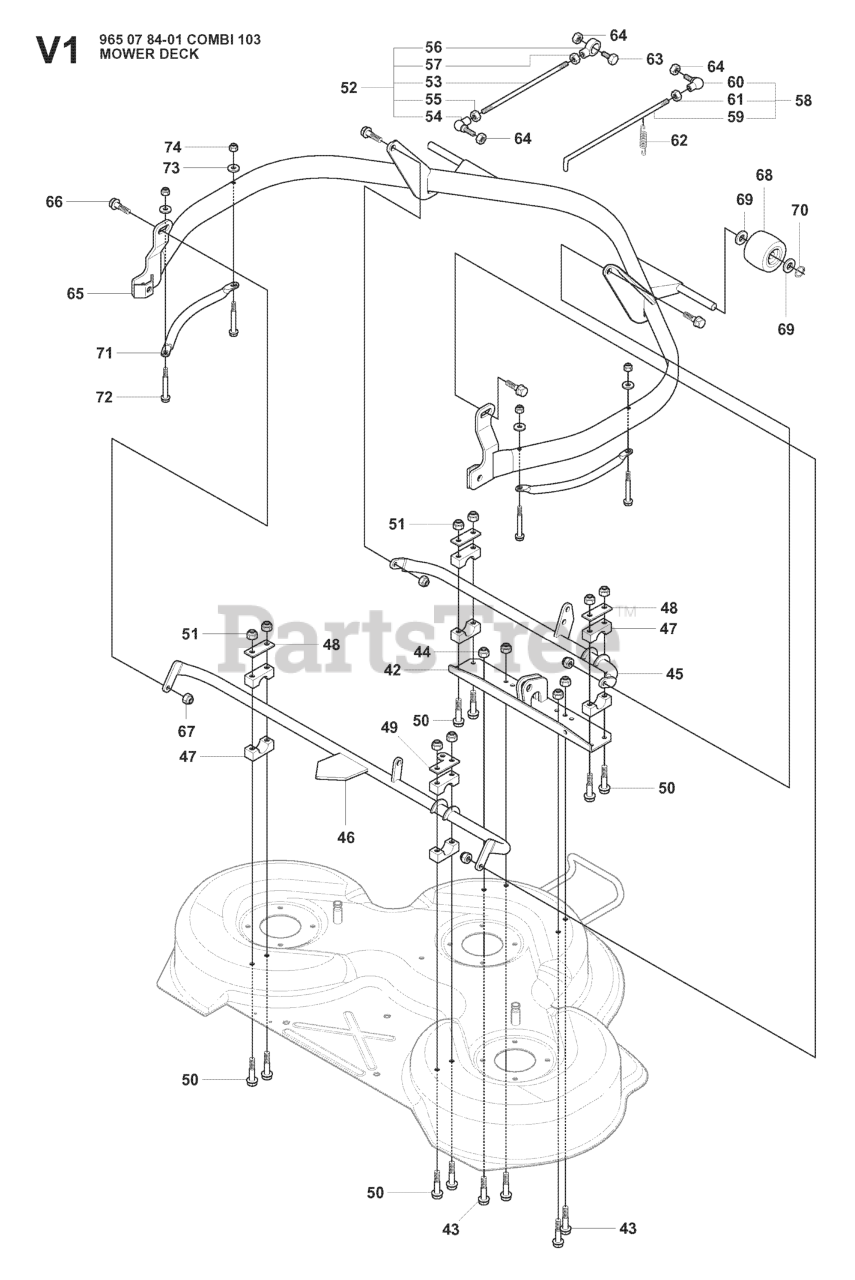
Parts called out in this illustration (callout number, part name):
44	LOCKNUT M8
51	LOCKNUT M8
52	PARALLEL RODY ASSY
57	NUT
58	CLUTCH ROD ASSY
64	NUT
65	PROTECTIVE TUBING
67	LOCKNUT M8
68	DECK ROLLER, FRONT
70	RETAINING RING SGA 15
73	WASHER
74	LOCKNUT M6
